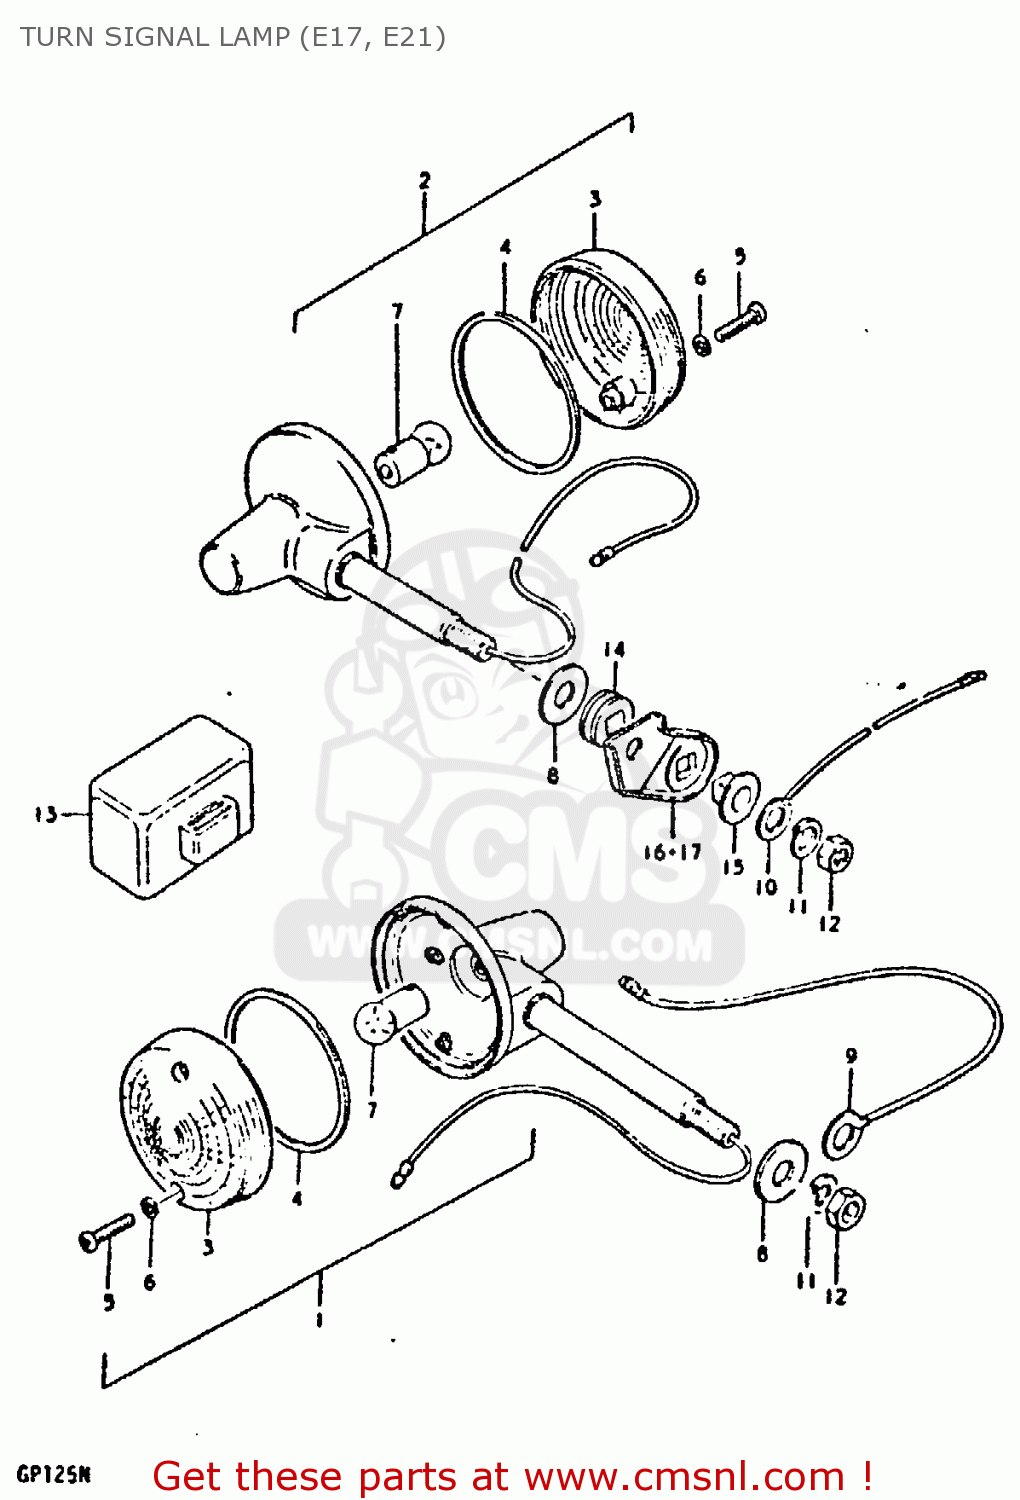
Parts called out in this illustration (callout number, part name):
1	LAMP, FRONT TURN SIGNAL
2	LAMP, REAR TURN SIGNAL
3	LENS
4	GASKET (NAS)
5	SCREW
6	GASKET (NAS)
7	BULB(6V/10W,STANLEY,A4117)
8	WASHER (10.5X30X2.3)
13	RELAY ASSY, TURN SIGNAL
